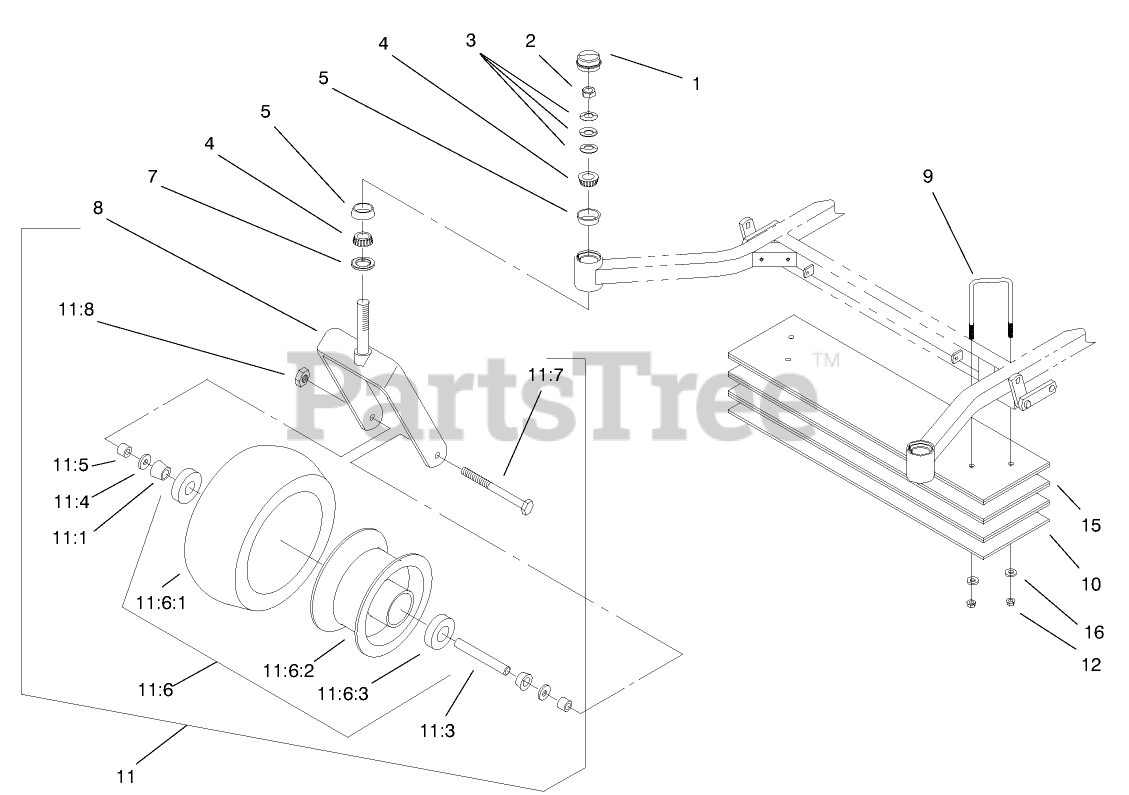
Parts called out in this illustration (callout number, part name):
1	Cap-Grease
2	LOCKNUT
3	Washer-Bellevue
4	BEARING-CONE, TAPERED
5	BEARING-CUP, TAPERED
7	Seal-Grease
8	Caster
9	U-BOLT
10	BAR-WEIGHT
11	Caster Wheel ASM
11:1	BEARING-CONE
11:3	Spacer
11:4	Seal-Bearing
11:5	Spacer-Bearing
11:6	Wheel & Tire ASM
11:6:1	Tire
11:6:2	Wheel
11:6:3	BEARING-ROLLER, CUP
11:7	SCREW-HH
11:8	NUT-LOCK, NI
12	NUT-HHF, WHIZ
15	WEIGHT BAR ASM
16	WASHER-FLAT
